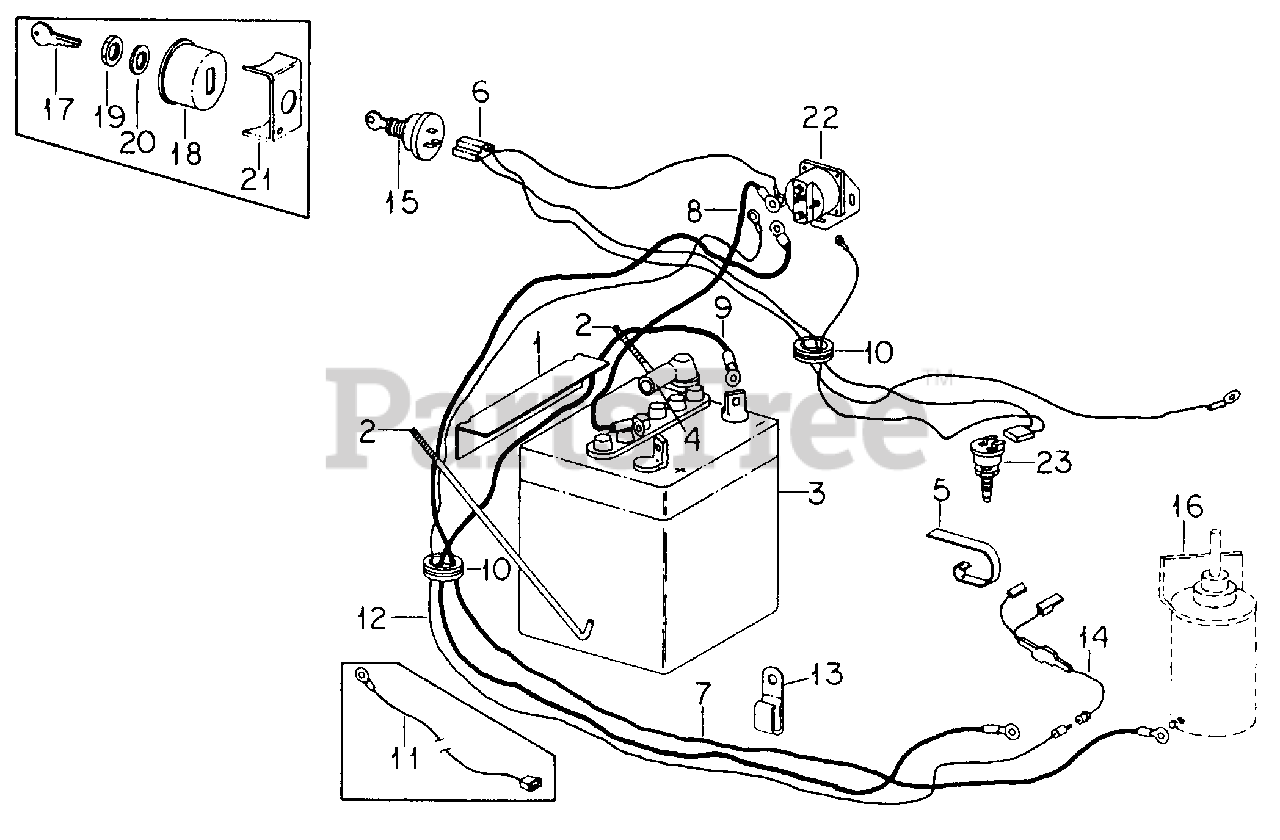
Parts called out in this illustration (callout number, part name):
1	Clamp, Battery Hold Down
2	Bolt, Battery Hold Down
3	Battery, Low Maintenance, 12 Volt
4	Cover, Battery Terminal
5	Spring, Neutral Start
6	Harness Assy, Cable
7	Cable Assy, Magnetic Switch to Starter
8	Cable Assy, Battery to Magnetic Switch
9	Cable Assy, Battery to Ground
11	Not used in this application
12	Cable Assy, Alternator to Magnetic Switch
13	Clip, Cable Harness
14	Not used in this application
15	Switch, Magneto Ignition & Starting
16	Motor Assy, Starter
17	Not used in this application
18	Not used in this application
19	Not used in this application
20	Not used in this application
21	Not used in this application
22	Switch, Magnetic
23	Switch Assy, Neutral Starting
